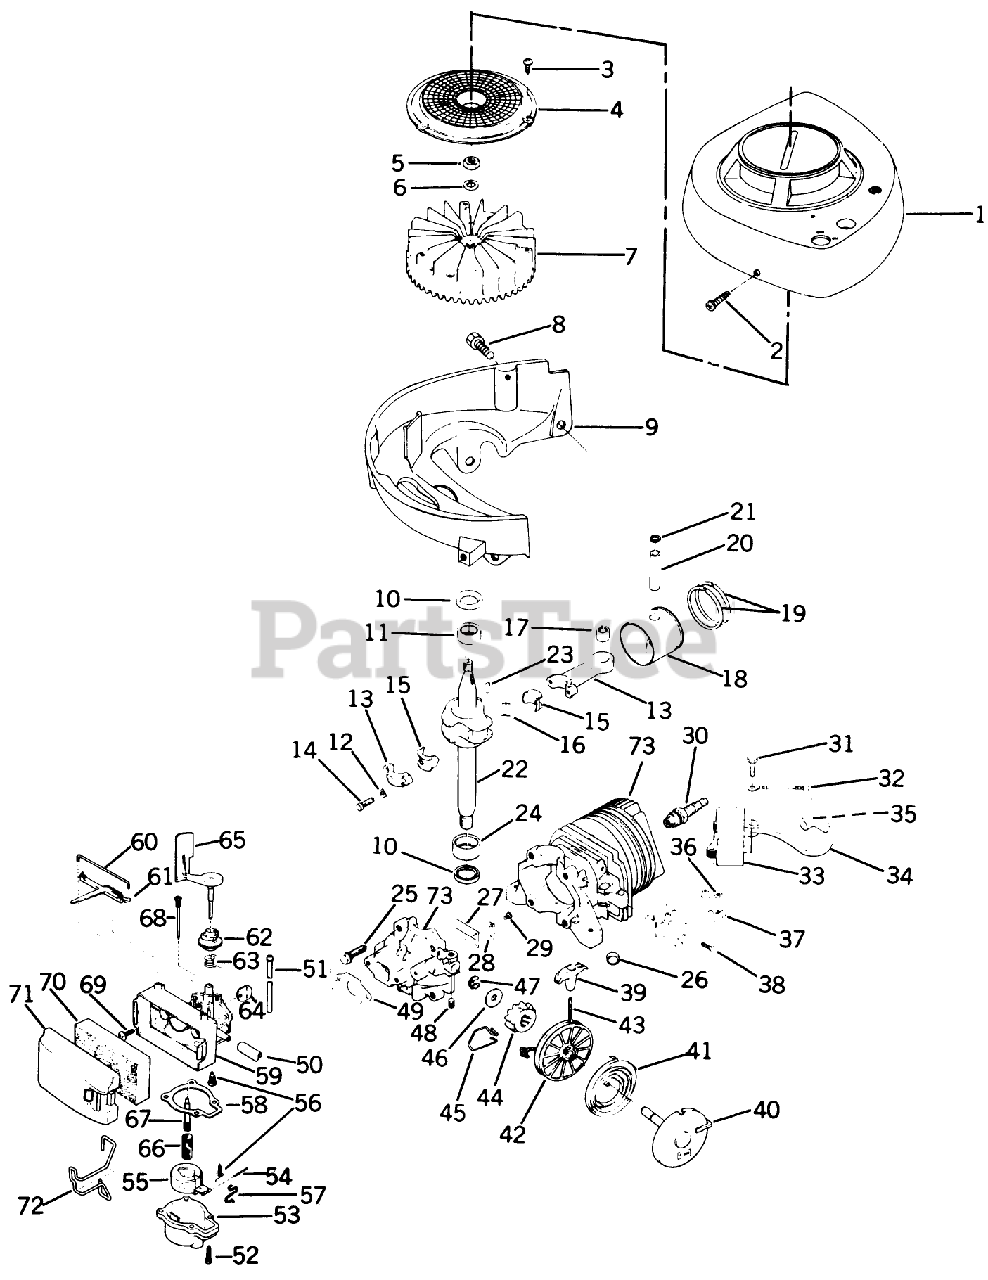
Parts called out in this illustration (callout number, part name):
2	SCREW F
3	SCREW F
5	NUT
8	SCREW-SEMS
11	BEARING V
12	Lockplate
14	SCREW
15	LINER ASM
17	BEARING AY F
21	RING-RETAINING
23	KEY
24	BEARING V
25	SCREW S
26	PLUG-CORE VF
28	PLATE-BACKUP, REED
32	TERMINAL S
34	HT LEAD&COVER XEV
36	NUT-CLIP
37	BRACKET S
39	HANDLE STARTER S
41	SPRING S
45	SPRING F
46	WASHER S
49	GASKET CARB S
51	TUBING PRIMER S
52	SCREW-HH
59	CARB BODY S
60	RETAINER
61	LEVER S
62	COLLAR-ADJUST, AIRVANE
63	SPRING,THROTTLE S
64	DISC S
65	AIR VANE&SHAFT S
66	FILTER-FUEL VS
68	NEEDLE ADJ. AY S
69	5238 19 LAWN-BOY MOREV1
72	RETAINER-COVER, FILTER
